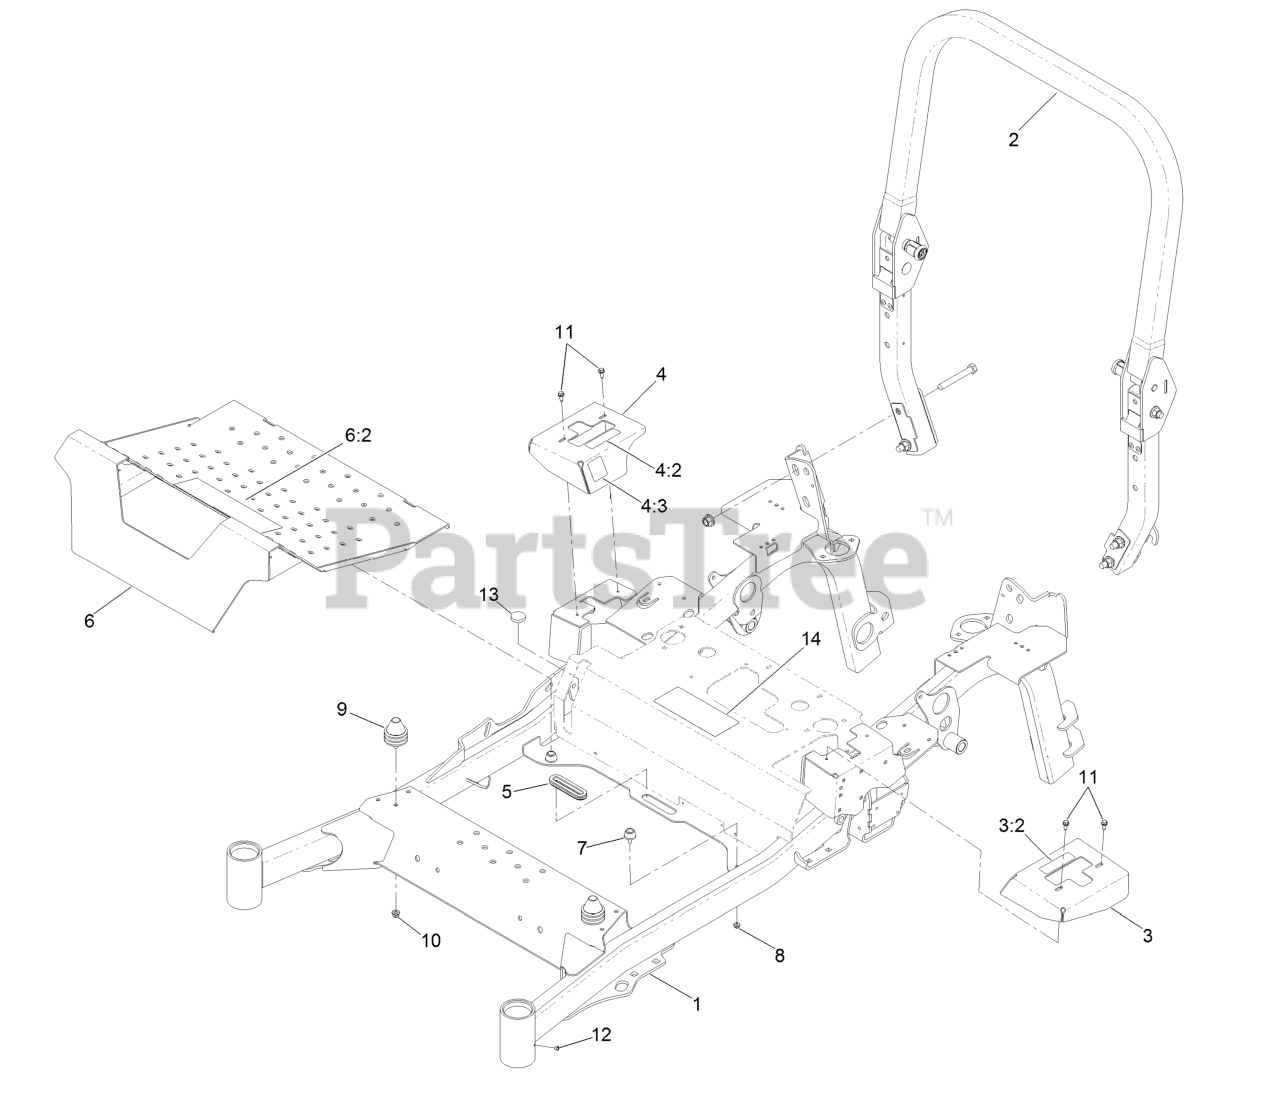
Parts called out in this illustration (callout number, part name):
1	Frame
2	ROPS ASM
3	Cover-Motion Control, LH
3:2	Decal-Control, Motion
4	Cover-Motion Control, RH
4:2	Decal-Control, Motion
4:3	Decal-Park Brake, CE
5	Grommet-Rubber
6	Pan-Floor
6:2	Decal-Danger
7	Bumper-Rubber
9	Isolator
10	Nut-HF, NI
11	Screw-HWH
13	Bumper-Push-In, Rubber
14	Decal-Service Aid
